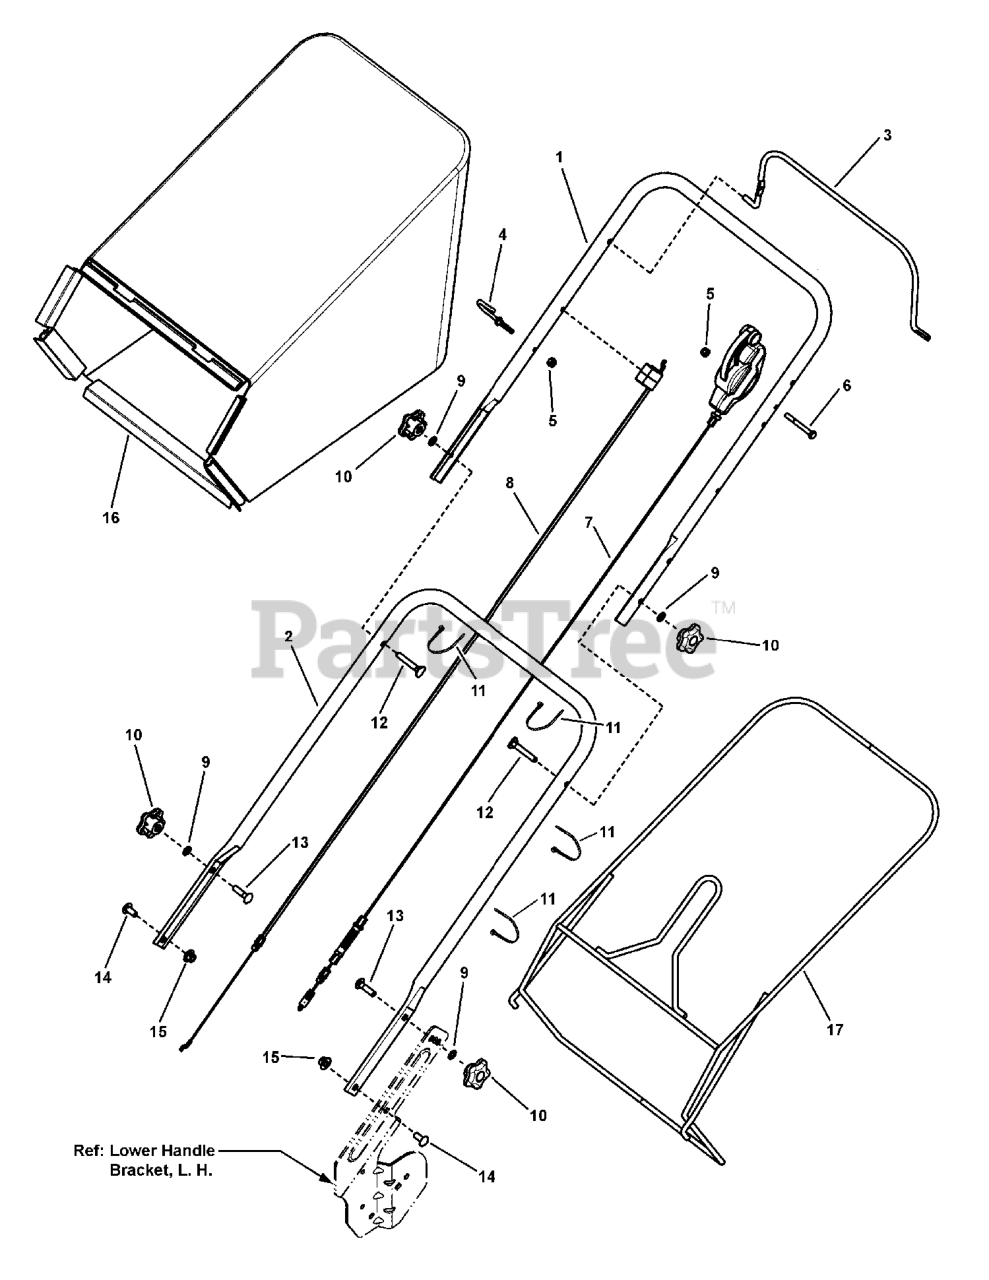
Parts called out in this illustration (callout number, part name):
1	UPPER HANDLE, Propelled
2	HANDLE, Lower
3	BAIL, OPC Propelled
4	Guide, Rope
5	NUT, 1/4-20 Nyloc
6	CAPSCREW, Hex Head, 1/4-20 x 2-1/4", GR 5
7	CONTROL, Drive, Single Speed
8	CABLE, Bail, Self-Propelled, Hi-Wheel
9	WASHER, Internal Tooth Lock, 5/16"
10	KNOB, Handle
11	WIRE TIE, 11 Inch Std Black Nylon
12	BOLT, Curved Head Square Neck, 5/16-18 x 2", GR 2
13	BOLT, Carriage, 5/16-18 x 1"
14	BOLT, Carriage, 5/16-18 x 3/4"
15	NUT, Hex, 5/16-18
16	GRASS BAG, Cloth, Murray
17	WELDMENT, Frame, Grass Bag
